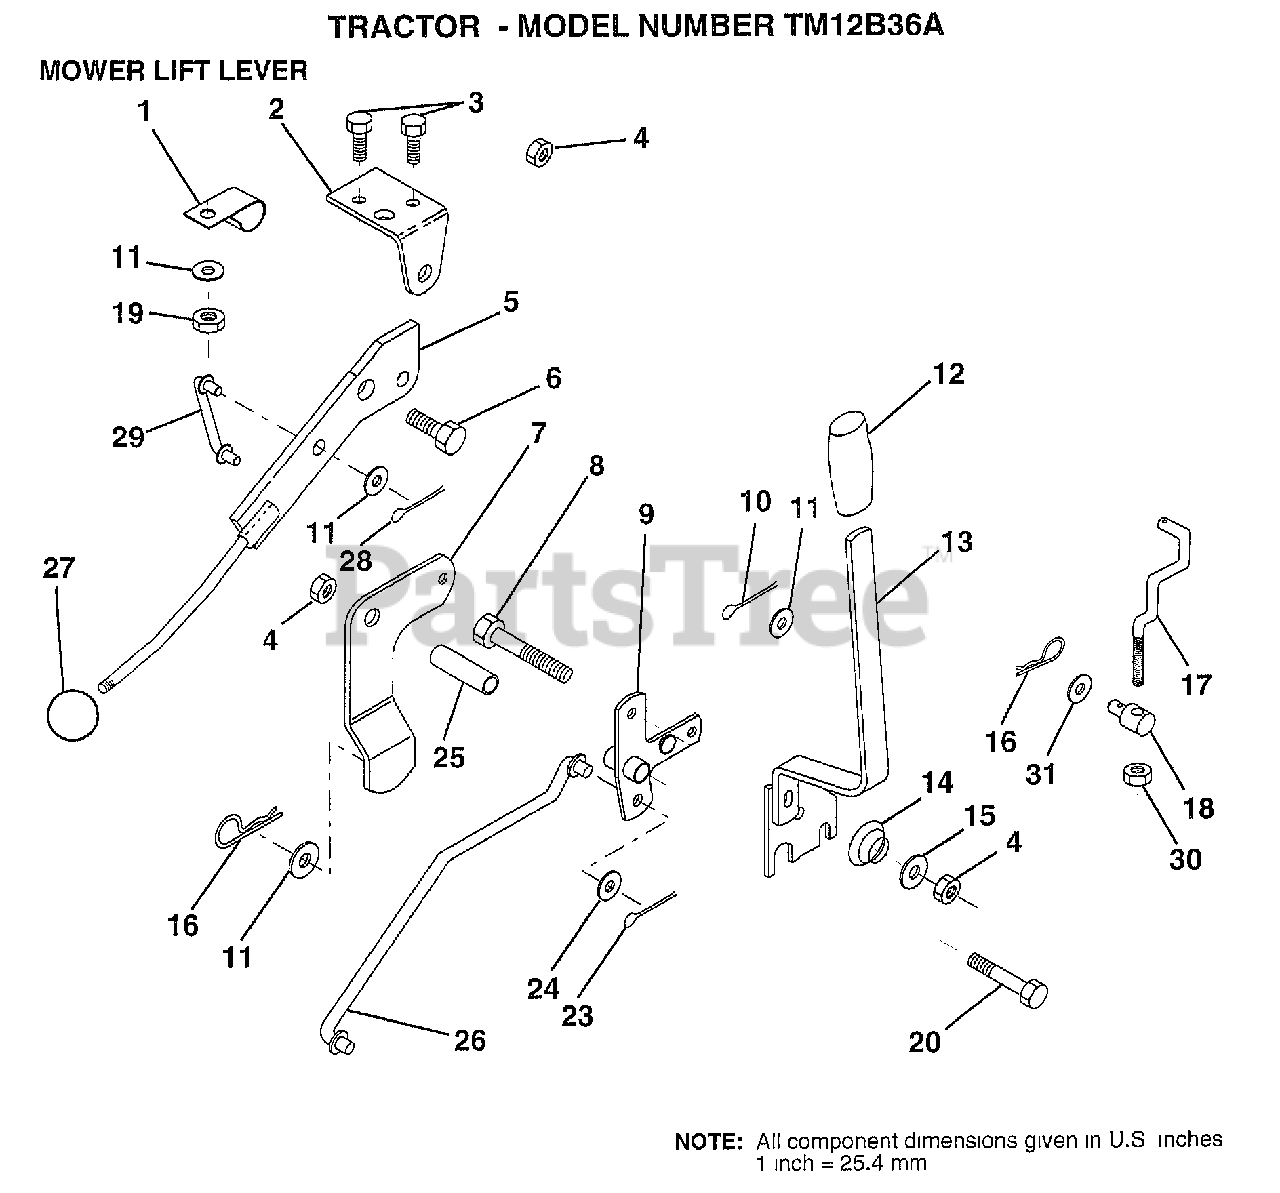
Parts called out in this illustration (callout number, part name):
1	"CLIP,INSULATOR"
2	BRKT CLUTCH
3	BOLT HXHD FIN
5	LEVER.ASM.CLUTCH
6	"BOLT, SHOULDER LT"
7	MWR CLUTCH ARM AS
8	BOLT
9	"BELLCRANK,LIFT"
10	COTTER PIN
11	WASHER
13	HANDLE.ASM.LIFT
14	SPRING COMPRESSIO
15	WASHER T
16	SPRING.RETAINER
17	"LINK,LIFT FRT"
18	TRUNION ADJ
20	BOLT
23	PIN COTTER 1/8
25	TUBE SPACER
26	ROD LIFT MOWER
27	KNOB T(3/8 HOLE)
29	CLUTCH LINK
30	NUT
31	WASHER
